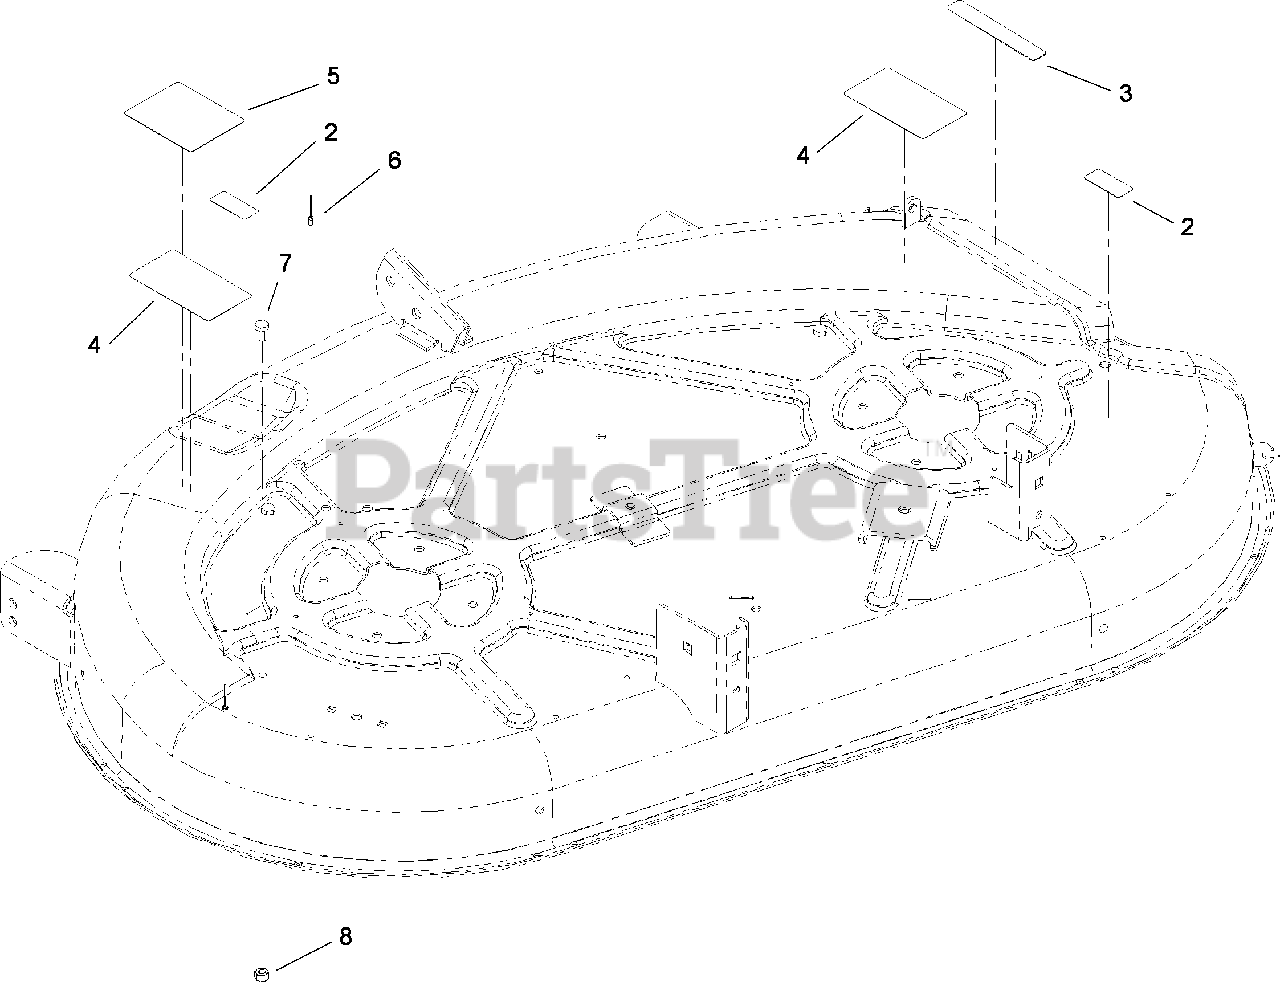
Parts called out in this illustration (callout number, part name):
2	DECAL-DANGER, PULLEY
3	DECAL-DANGER
4	DECAL-DANGER
5	DECAL-ROUTING, BELT
6	RIVET-POP
7	SCREW-HH
8	NUT-LOCK, NI
